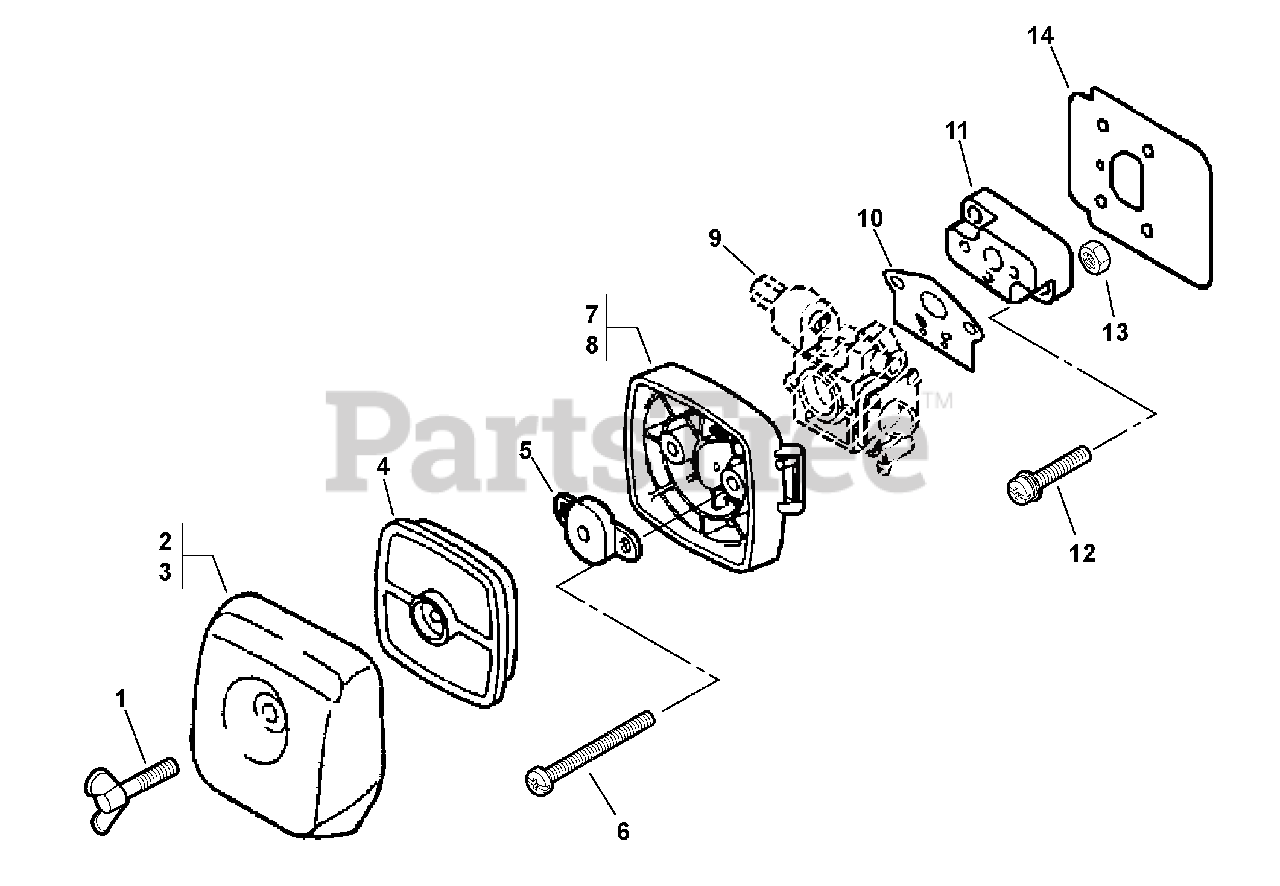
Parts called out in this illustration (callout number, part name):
1	BOLT, WING 5×20
2	COVER, AIR FILTER - GRAY
3	COVER, AIR FILTER - BLACK
4	FILTER, AIR - SINGLE LAYER
5	PLATE, PREVENT
6	SCREW 5×65
7	CASE, AIR FILTER - GRAY
8	CASE, AIR FILTER - BLACK
9	CARBURETOR
10	GASKET, CARBURETOR
11	INSULATOR, INTAKE
12	SCREW 5×20
13	NUT M5
14	HEAT SHIELD, INTAKE
